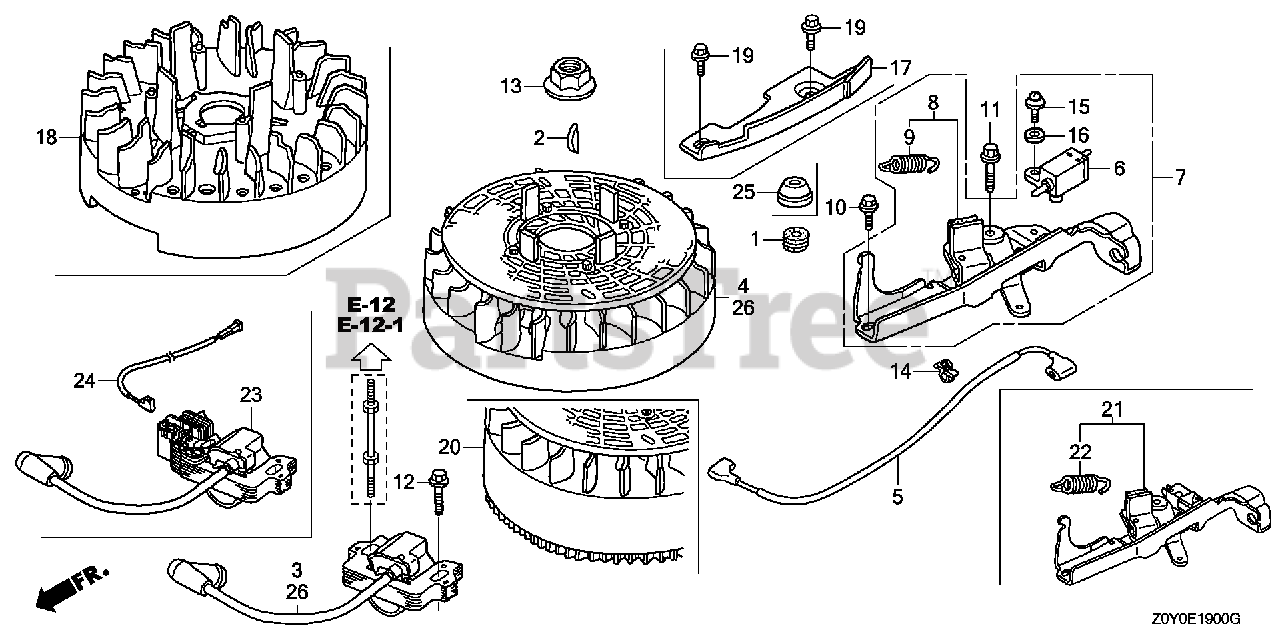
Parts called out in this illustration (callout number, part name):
2	KEY, SPECIAL WOODRUFF (25X18)
3	COIL ASSY., IGNITION (PHELON) (USE FOR F/W OF PHELON)
3	COIL ASSY., IGNITION (PHELON)
10	BOLT, FLANGE (6X14) (CT200)
11	BOLT, FLANGE (6X23) (CT200)
12	BOLT, FLANGE (6X20) (CT200)
13	NUT, FLANGE (14MM)
14	CLIP A, CABLE (3.8MM BLACK) (NIFCO)
20	FLYWHEEL ASSY. (PHELON) (USE FOR IGN. COIL OF PHELON) (NA USE ALT:31105-Z0Y-922)
21	BRAKE SUB-ASSY.
22	SPRING, BRAKE LEVER
